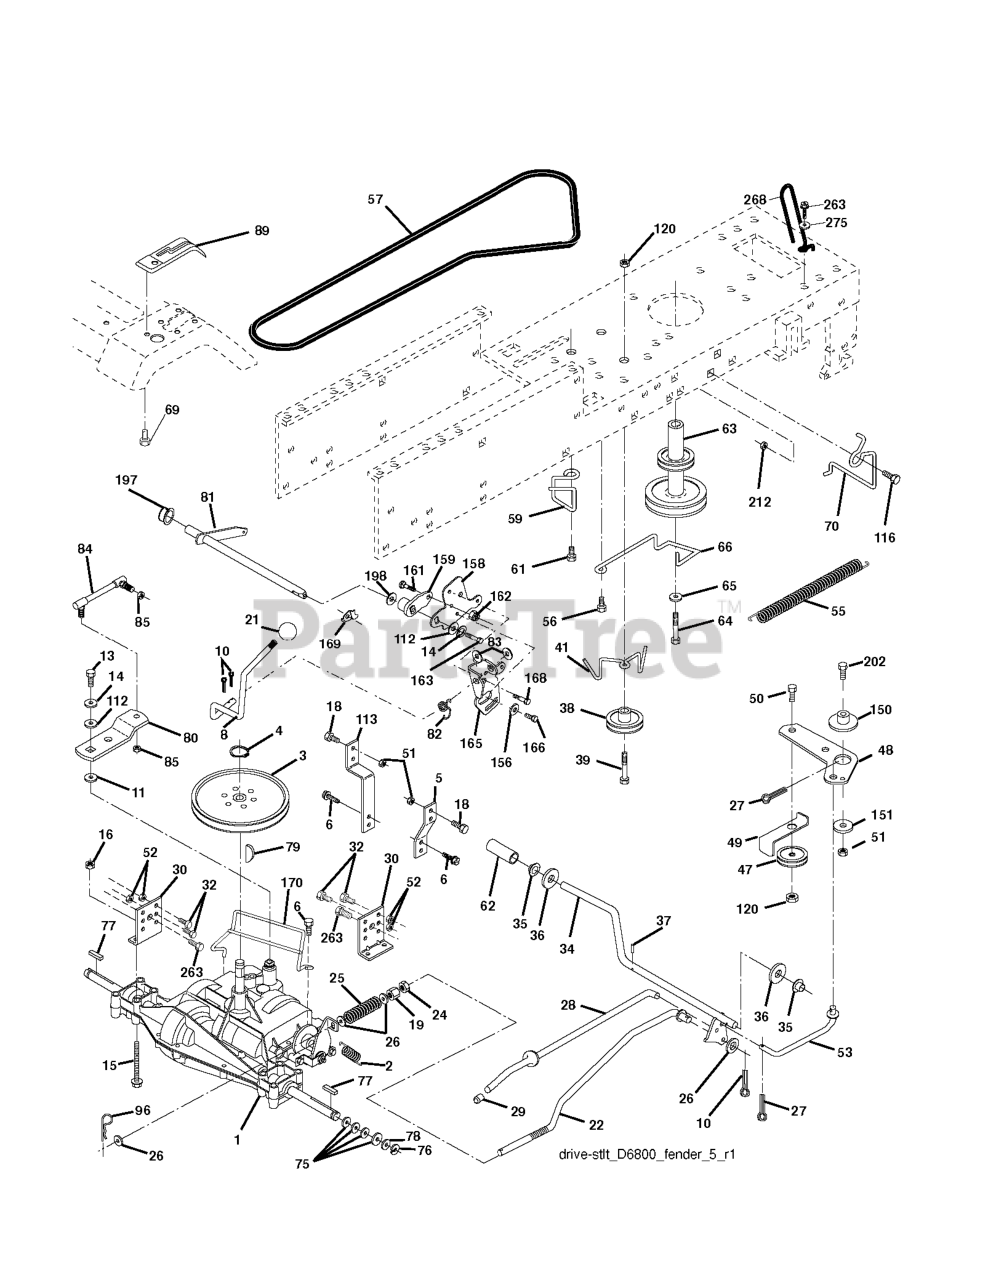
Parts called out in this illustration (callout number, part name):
2	SPRING,BRAKE RETURN
3	PULLEY TRANS
4	RETAINING RING LT
5	STRAP TORQUE
6	SCREW 5/16"
8	ROD SHIFT FENDER ADJUST LT
10	PIN COTTER
11	WASH-SHFT PLT LT
13	BOLT 1/4-28X3/4
14	LOCKWASHER
15	BOLT HEX 5/16-18 GR 5
16	NUT.71038.31-18.HEX.NYLOCK
19	NUT
21	KNOB T (1/2-HOLE)
24	NUT
25	SPRING ROD LT
26	WASHER
27	COTTER PIN
28	ROD, PARKING BRAKE
29	PLUNGER CAP
30	BRKT, MOUNT TRNSAXLE
32	BOLT
34	SHAFT, FOOT PEDAL
35	BEARING.NYLON
37	DRIVE PIN
38	PULLEY IDLER COMPOSITE
41	KEEPER, BELT IDLER
47	IDLER PULLEY
48	BELLCRANK, CLUTCH
49	RETAIN BELT
50	BOLT.3/8-16X1.50
52	LOCKNUT
53	LINK.CLUTCH.7.66.2005
55	SPRING, RETURN LT
56	SCREW.3/8-16
59	KEEPER, BELT CENTER
61	SCREW 3/8-16X.875
62	PEDAL COVER T
63	ENGINE PULLEY
64	BOLT HEX 7/16-20X4-1/4"
65	LOCKWASHER
66	KEEPER BELT ENGINE
69	SCREW.HI-LO.CONSOLE
70	KEEPER BELT ENG
77	SQUARE KEY
79	KEY STD (1373) DANA
81	SHAFT ASM CROSS TAPERED
82	SHIFT SPRING
83	WASHER
84	LINK.TRANSAXLE.DANA/18
85	NUT LOCK CENTER 1/4 -28 FNTHD
89	CONSOLE.SVC.SHIFT.LTST.5SP.BLK
96	RETAINER M
113	STRAP TORQUE LH LT
116	BOLT D
120	NUT LOCK FLG 3/8-16 UNC
150	SPACER, RETAINER
151	WASHER 12/32X2X10GA
156	WASHER.SRRTD.5/16
158	BRACKET
159	RB HUB.SHIFT
161	BOLT
162	NUT.CROWNLOCK.1/4
165	RP BRACKET
166	CAPSCREW.HXHD.FLG.5/16-18X.625
168	BOLT.SHOULDER.5/16-18X
169	PLATE.FASTENING.CROSS.SHAFT
170	KEEPER BELT T/A
197	NYLINER SNAP 5/8" ID
198	WASHER.NYL.7/8IDX.105"HYD CR
212	NUT
263	SCREW, 3/8-16X3/4
268	GUARD MUFFLER
275	WASHER
